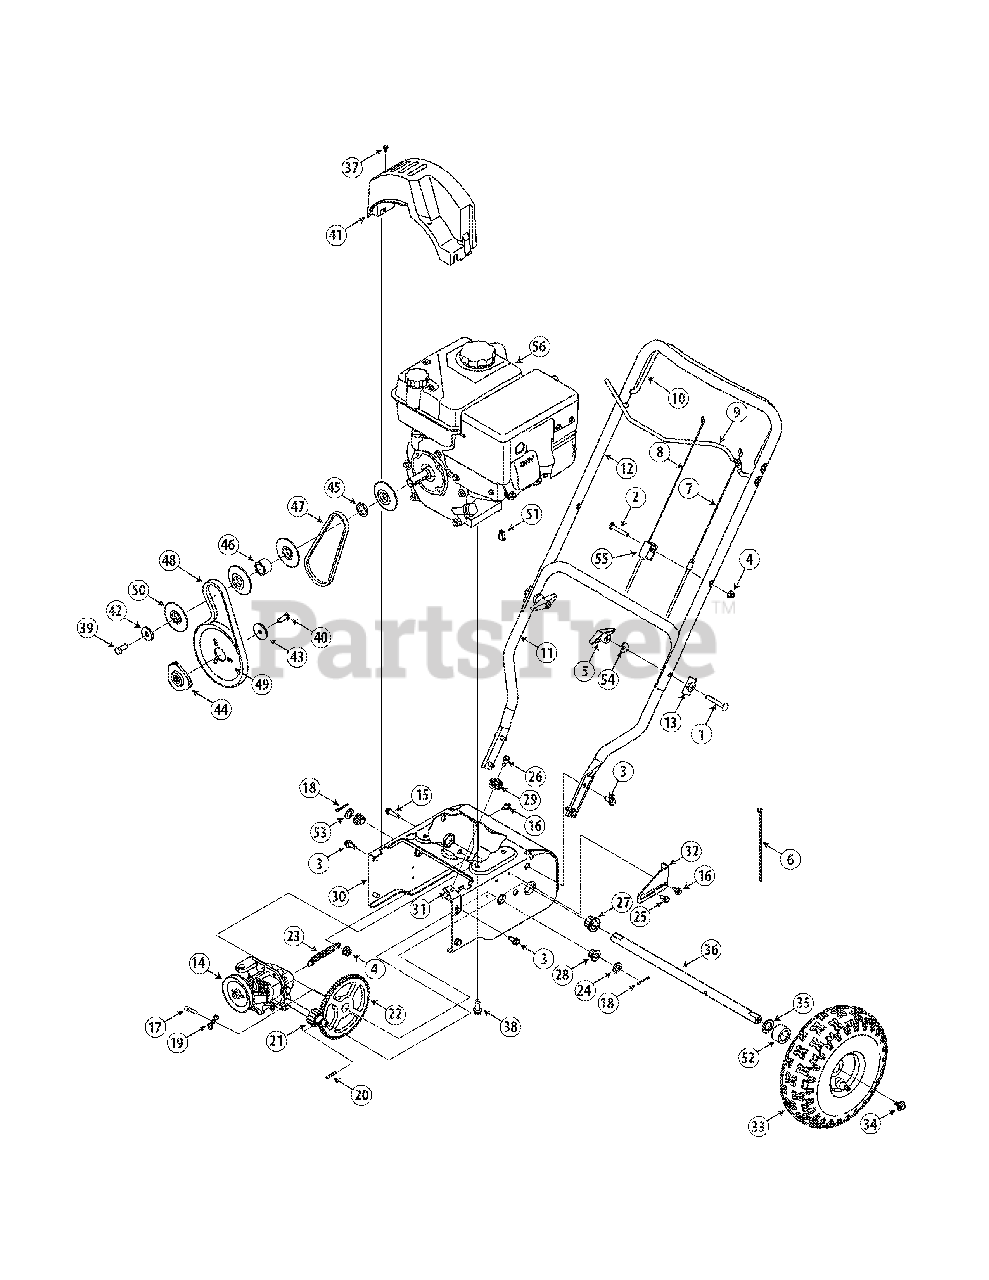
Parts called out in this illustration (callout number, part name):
1	Carriage Screw 5/16-18 x 2.25
2	Mach. Screw, 1/4-20 x 1.50
3	Screw 5/16-18 x .75
4	Flange Lock Nut 1/4-20
5	Wing Knob 5/16-18
6	Cable Tie
7	Drive Cable
8	Auger Cable
9	Auger Control
10	Drive Control
11	Lower Handle
12	Upper Handle
13	Handle Tab
14	Transmission Assembly
15	TT Screw 1/4-20 x 1.25
16	Screw 1/4-20 x .625
17	Clevis Pin
18	Cotter Pin 1/8 x 1.0
19	Bow Tie Cotter Pin 72
20	Roll Pin
21	Pinion 14T
22	Gear 70T
23	Extension Spring
24	Flat Washer
25	Shoulder Screw 1/4-20
26	Shoulder Screw 1/4-28
27	Hex Flange Bearing
28	Hex Flange Bearing
29	Cable Roller
30	Drive Housing Frame
31	Auger Cable Bracket
33	Wheel Assy Snow Hog Gray
33	Tube, Tire, 4.10/3.50-4.0
34	Screw, 5/16-24 x .750
35	Flat Washer, .793 x 1.24 x .06
37	Hex Screw #10-16 x .500
38	TT Sems Screw 3/8-16 x 1.0
39	Hex Bolt 3/8-24 x .875
40	Lock Bolt 5/16-24 x .875
41	Belt Cover
42	Flat Washer .45 ID x 1.5 OD
43	Flat Washer .34 ID x 1.50 OD
44	Pulley: Adapter .75 Dia.
45	Flat Washer, .876 x 1.25 x .11
46	Spacer .876 x 1.25 x .11
47	V-Belt 3/8 x 21.108 Lg.
48	V-Belt 3/8 x 26.375 Lg.
49	Auger Pulley
50	Pulley Half
51	Amp Sealed Connector
53	Flat Washer .53 x .93 x .05
54	Saddle Washer
55	Cable Clip
56	Complete Engine
